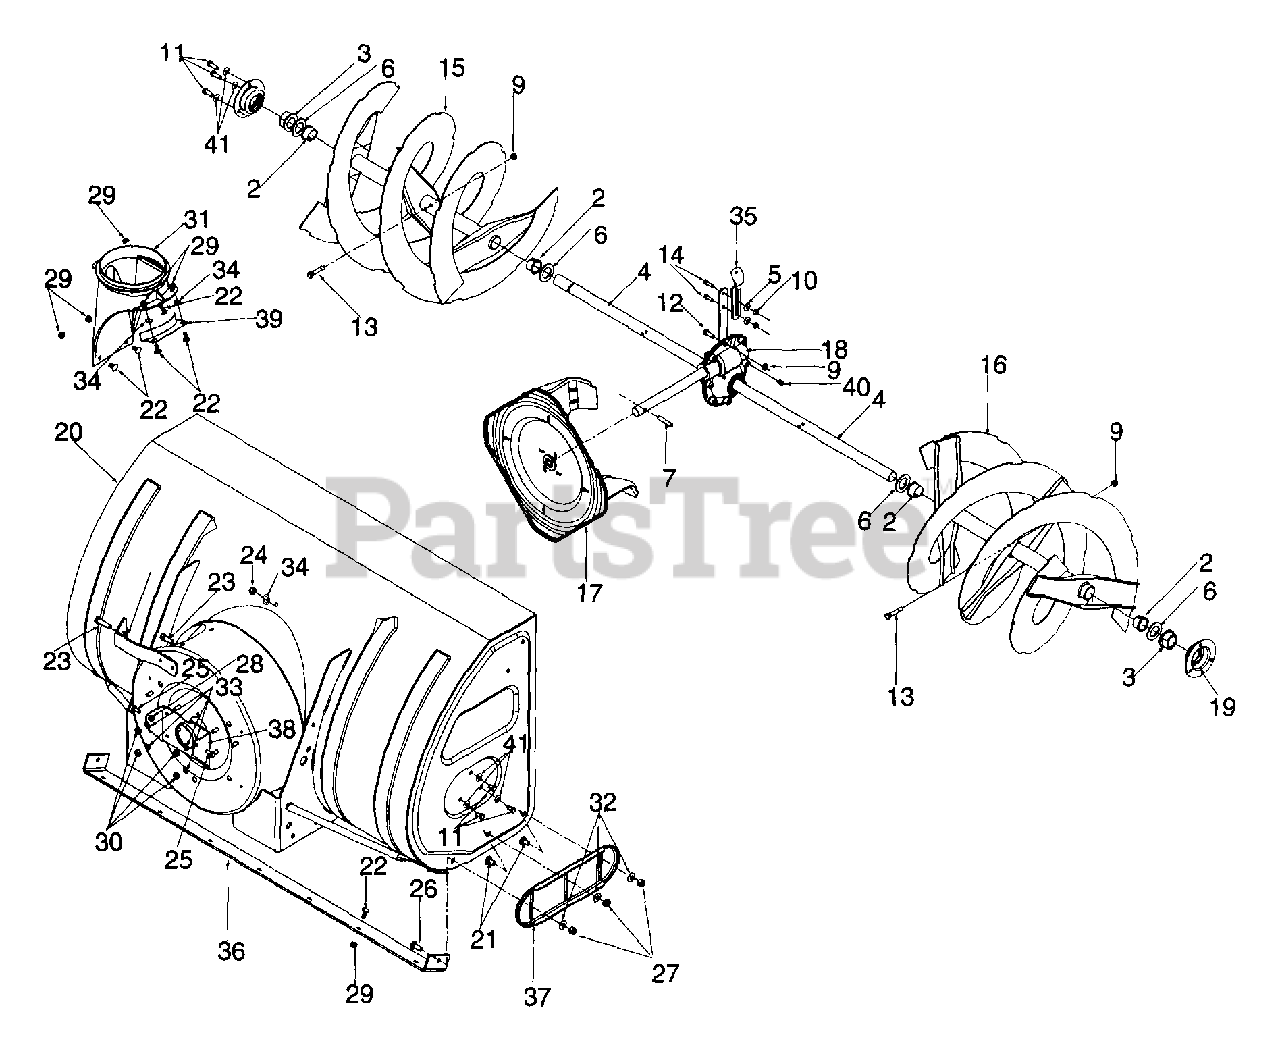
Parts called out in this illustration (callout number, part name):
1	Pit:Supt.
2	Bush:Fig:1.05 I.D. x 1.16 O.D.
3	Brg:Flg:w/Flats
4	Spiral Axle 1.00 X 44.12
5	Wash: Bell:.265 x .75 x .062
6	Fl. 1.00 1.D. x 1.75 O.D. X .1
7	Spring Pin Spir 5/16 Dia. X 1.7
9	Hx. Nut:: 5/16-18:Gr.C:Lock
10	Hx. Nut:1/4-28:Gr.A
11	Scr. TT Hx Ind Wash 5/16-18:.625 Lg
12	HHCS:5/16-18:.875:Gr.5:Std.
13	Shear Bolt 5/16 - 18 x 1-3/4
14	HHCS:1/4-28:.75:Gr.5:Std.
18	Gear Asm:Auger
19	Hsg:Brg:1.50 DBL-T
22	Bolt:Car:5/16-18:.75
23	HHCS:3/8-16:1.50:Gr.5:Std.
24	Scr:AB:5/16-12:0:.750: Hx Ind Wsh
25	HHCS:1/4-20:.75: Gr.5: Std.
26	Bolt:Carr:3/8-16
27	Nut: Hx.:3/8-16:Gr.C:Lock
28	Nut:Hx: 1/4-20:Gr.C:Lock
29	Nut:Hx: 5/16-18:Gr.C:Lock
30	Hx. Nut: 5/16-18:Gr.B
31	Chute: Adap:6" Dia.
32	Wash:Spr:.401 x .870 x .063
33	Wash:Lock: 5/16:Regular Duty
34	Wash: Belvl:.340 I.D. x .872 O.D.
35	Gear Housg.Supp.Brkt
36	Pit: Shave
38	Brkt:Mt: Brg.
39	Brkt:Chut:6.0
40	Woodruff Key 1/4 x 3/4 Dia.
41	Wash. Bell .340 I.D. x .872 O.D.
